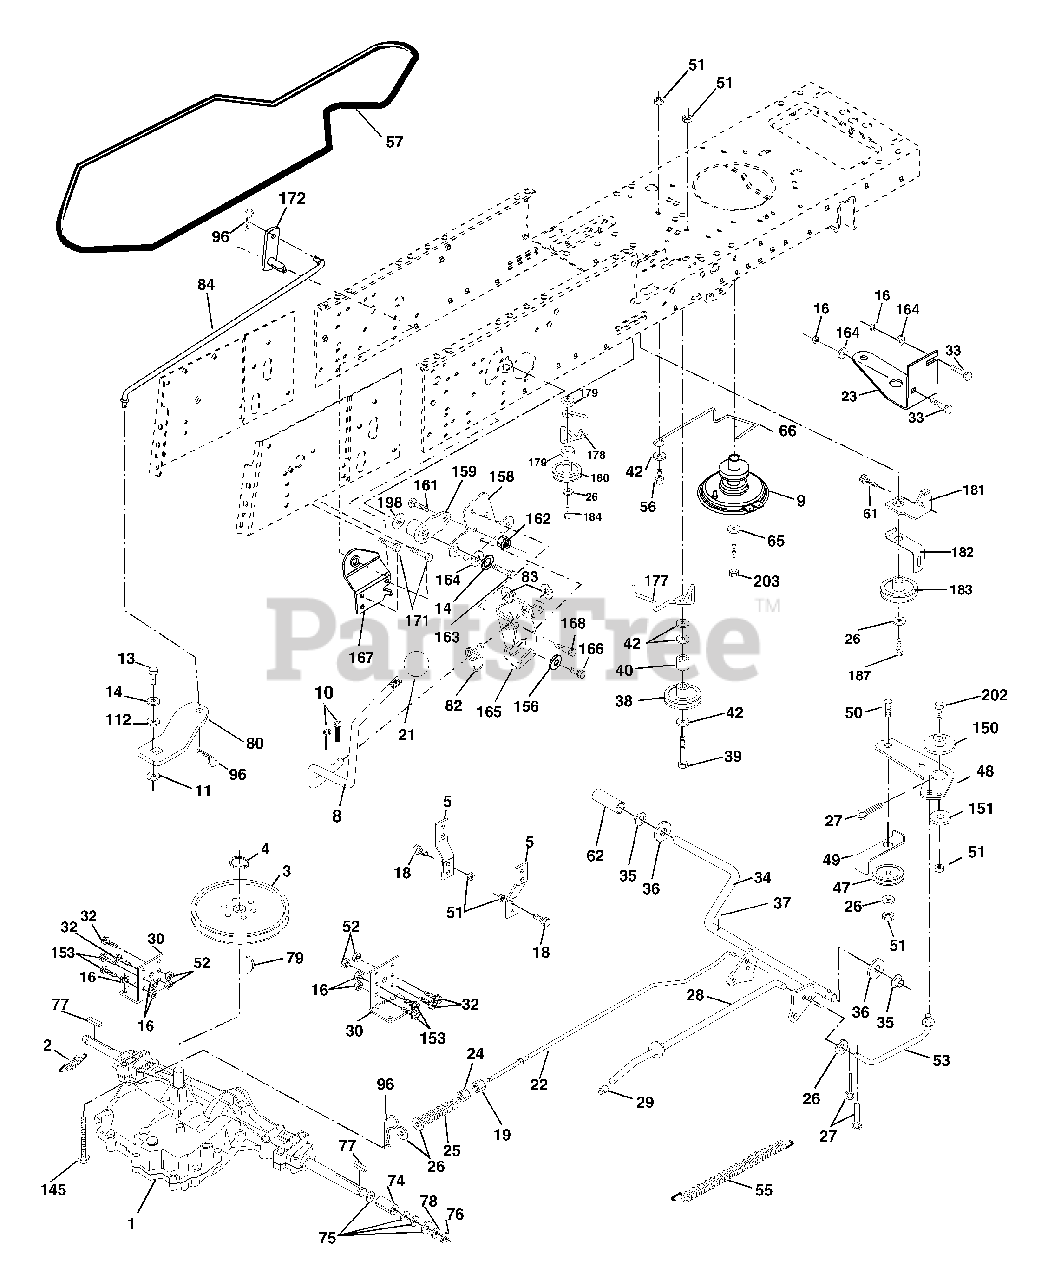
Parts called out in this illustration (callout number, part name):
2	Spring Brake Return
3	Pulley Transaxle
4	Ring Retainer #5100-62
5	Strap torque 30 degrees
8	Rod Shift Fender Adjust Lt
9	Clutch Asm Noram
10	Pin, Cotter 1/8 x 1
11	Washer Plate Shf .3888 sq hole
13	Bolt 1/4-28 Unf Gr 8 w/patch
14	Washer, Lock Hvy Helical
16	Nut, Lock Hex w/Ins 5/16-18 UNC
18	Bolt Hex 3/8-16 UNC x 1 Gr.5
19	Nut, Lock Hex w/Wsh 3/8-16 UNC
21	Knob Duckhead 1/2-13 Unc Blk
22	Rod, Brake CRD 0650
23	Bracket Pnt Clutch Noram
24	Nut
25	Spring, Rod, Brake
26	Washer 13/32 x 13/16 x 16 Ga.
27	Pin, Cotter 1/8 x 3/4
28	Rod, Parking Brake
29	Cap, Parking Brake
30	Bracket, Mfg. Transaxle
32	Bolt Hex 5/16-18 UNC x 3/4
33	Bolt Rdhd Sqnk 5/16-18 Unc x 3/4
34	Shaft, Asm Pedal Foot CRD
35	Bearing, Nylon
36	Washer 21/32 x 1 x 16 Ga.
37	Pin, Roll 3/16 x 1"
38	Pulley, Flat
39	Bolt Rdhd 3/8-16 UNC x 2-3/4 Gr. 5
40	Spacer, Split 395 x 59 Bzp
42	Washer 13/32 x 13/16 x 12 Ga.
47	Pulley, Idler, V Groove Plasitc
48	Bellcrank Clutch Grnd Drv
49	Retainer, Belt Style Spring
50	Bolt Hex Hd 3/8-16 UNC x 1-1/2
51	Nut, Crownlock 3/8-16 UNC
52	Nut Crownlock 5/16-18
53	Link, Clutch 7.66
55	Spring, Return, Clutch
56	Bolt, Hex 3/8-16 UNC x 1-1/4
57	V-Belt Kev PMST CRD
61	Screw 3/8-16 x 3/4
62	Cover, Pedal
63	Pulley, Clutch elect EVX 1"
65	Washer
66	Keeper, Belt Engine F-Proof
74	Spacer Axle
75	Washer 25/32 x 1-1/4 x 16 Ga.
77	Key, Square
78	Washer 25/32 x 1-5/8 x 16 Ga.
79	Key Woodruff
80	Arm Shift PMST 20" Tires
82	Spring, Torsion
83	Washer 17/32 x 3/4 x 16 Ga.
84	Link Shift CRD Pmst 18" Tires
96	Spring, Retainer 1"
112	Washer 9/32 x 3/4 x 10 Ga.
145	Bolt Hex FGHD 5/16-18 x Gr 5
150	Bushing, Bellcrank Grnd Dr
151	Washer 13/32 x 2 x 10 Ga.
153	Bolt Hex Hd 5/16-18 Unc x 1
156	Washer Srred 5/16 ID x 1.125
158	Bracket Shift Mount
159	Hub Tapered Flange Shift Lt
161	Bolt Rdhd Sqnk 1/4-20 x 3/4 Gr 5
162	Nut Crownlock 1/4-20 Unc
163	Bolt Hex Fin 1/4-20 Unc x 1 Gr 5
164	Washer 5/8 x .281 x 10 Ga.
165	Bracket Pivot Lever
166	Screw 5/16-18 x 5/8
167	Bracket Support Shift CRD
168	Bolt Shoulder 5/16-18 x .561
171	Screw Thdrol 3/8-16 x 1/2 Ty-Tt
172	Shaft Asm Shift Front CRD PMST
177	Keeper Flat Idler 3.06" CRD
178	Keeper Belt Idler 1.88" CRD
179	Washer Sintered
180	Pulley Flat Composite 3.06"
181	Bracket Idler Ground Drive CRD
182	Keeper Belt 2.5" Od V-Idler CRD
183	Pulley V-Idler 2.50" Od CRD
184	Screw Hexwsh Thdrol 3/8-16 x 2-3/4
187	Screw Thdrol 3/8-16 x 1-1/4
188	Bushing Snap Split Blk
198	Washer Nyl 7/8 ID x .105" Hyd CRD
202	Bolt Carr Sh 3/8-16 x 1/2 Ty-Tt
203	Bolt Hex 7/16-20 x 5
